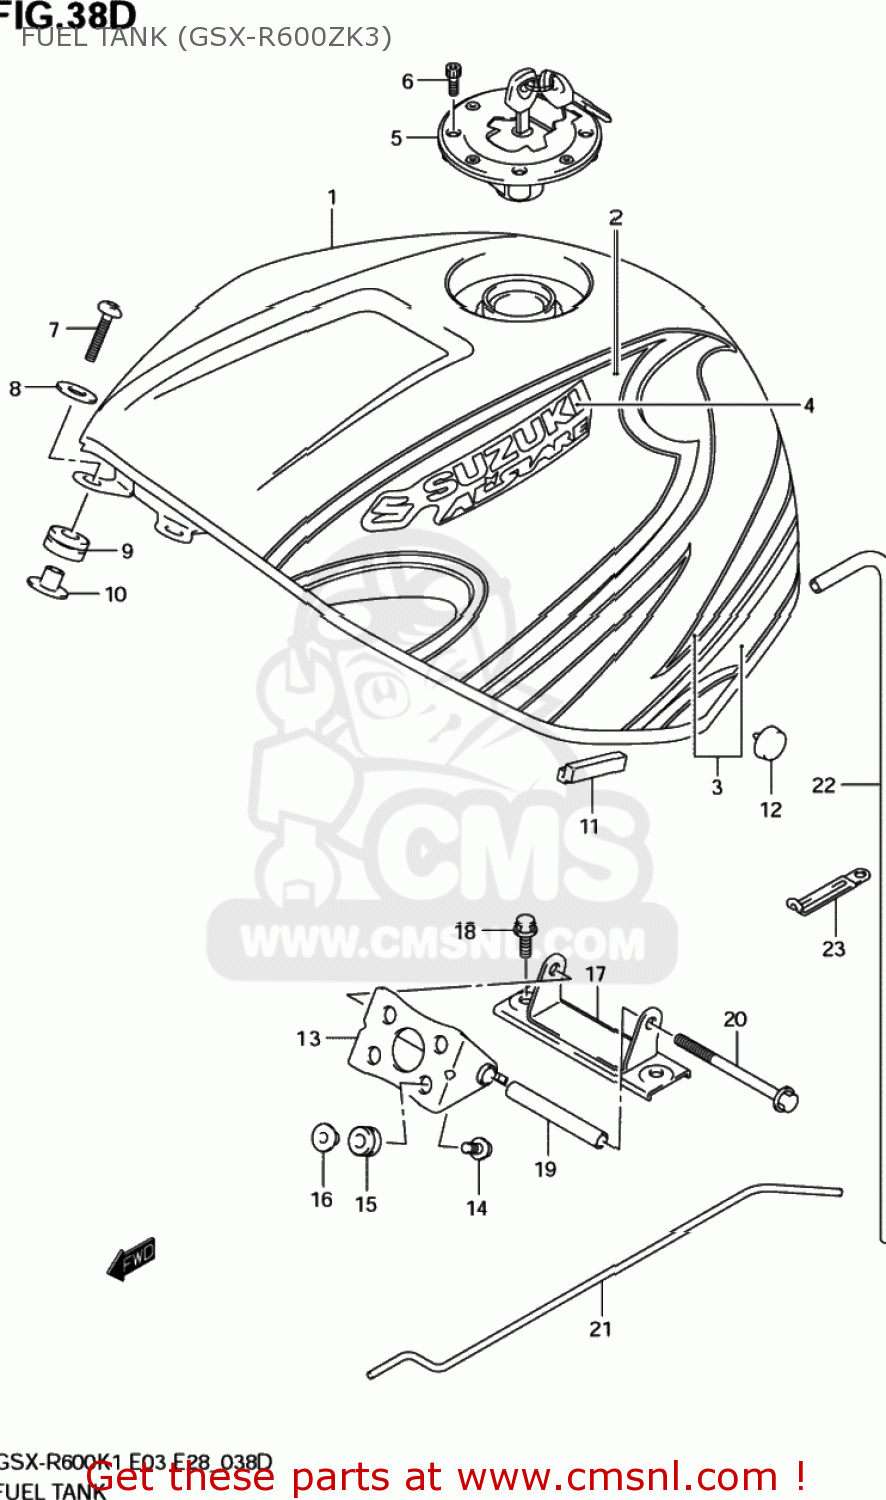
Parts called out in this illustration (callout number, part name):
1	TANK ASSY,FUEL
2	TAPE SET,FUEL TANK UPR
3	TAPE SET,FUEL TANK LWR
4	EMBLEM,FUEL TANK
5	CAP SET,FUEL TANK
6	BOLT(5X20)
7	SCREW(6X25)
8	WASHER(6.5X22X1.6)
9	CUSHION,FUEL TANK FR
10	SPACER,FUEL TANK FR
11	CUSHION,FUEL TANK SIDE
12	CUSHION,FUEL TANK SIDE NO.2
13	BRACKET,FUEL TANK NO.1
14	BOLT(6X20)
15	CUSHION
16	WASHER
17	BRACKET,FUEL TANK NO.2
18	BOLT
19	SPACER,FUEL TANK RR
20	BOLT
21	STAY,FUEL TANK
22	HOSE,FUEL TANK WATER DRAIN
23	CLAMP(L:65)
